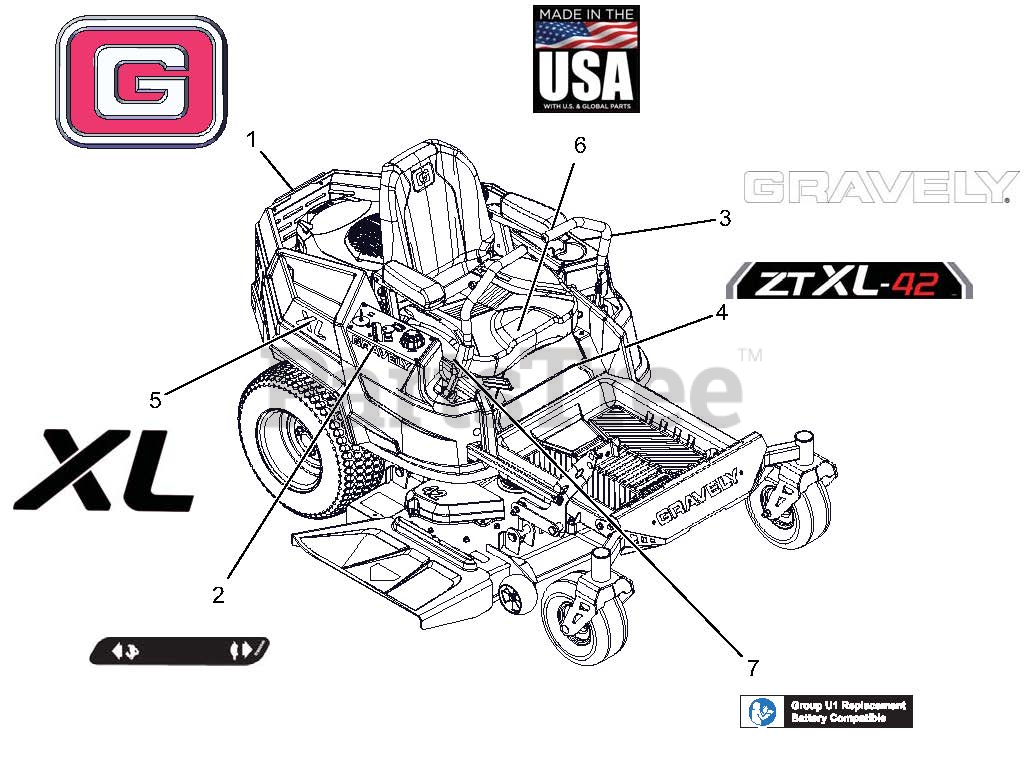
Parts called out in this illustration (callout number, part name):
1	DECAL, GRAVELY BRAND
2	DECAL, DASH DECAL
3	DECAL, 9.5" GRAVELY LOGO
4	DECAL, ZT XL 42"
5	DECAL, "XL"
6	DECAL, MADE IN USA
7	DECAL, U1 BATTERY REPLACEMENT
